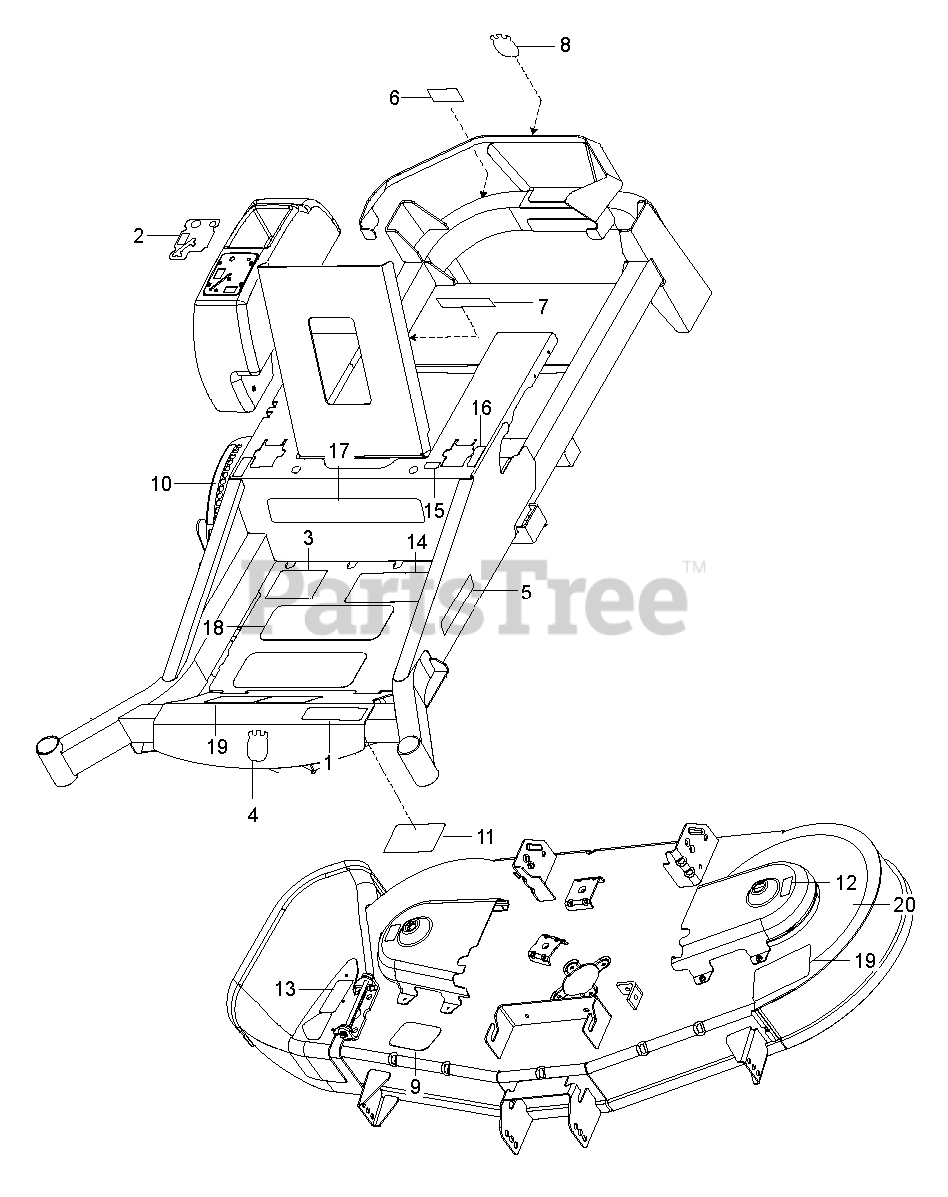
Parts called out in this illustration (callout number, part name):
1	DECAL ZTR MODEL NUMBER DECAL.Z
2	DECAL, CONSOLE HUS
3	DECAL.ZTR.STRTNGINST.REMOTECHK
4	DECAL.AUGER.HUSQ.CROWN.SNOW
5	RP.DECAL.BADGE.170MM.TEXTLOGO
6	DECAL, BELT DRIVE
7	EURO DECAL-BATTERY WARNIN6
8	DECAL, CROWN H, 110MM
9	DECAL BELT ROUTING DECAL DECAL
10	DECAL, HEIGHT ADJUST
11	DECAL, SERVICE
12	DECAL.DECK.CLEARCUT.NOSTEP
13	DECAL.TRACT/ZTR.DECKWARN.HUSQ
14	DECAL ZTR WARNING DECAL DECAL.
15	DECAL.STR.S.T.SYSMBOLONLY.2014
16	DECAL.ZTR.MOTCONTRL.SYMBOL.HUS
17	DECAL ZTR BRAND GRAPHIC DECAL.
18	ANTI-SKID PAD
20	DECAL.54DECK.CLEARCUT.VER2.18
